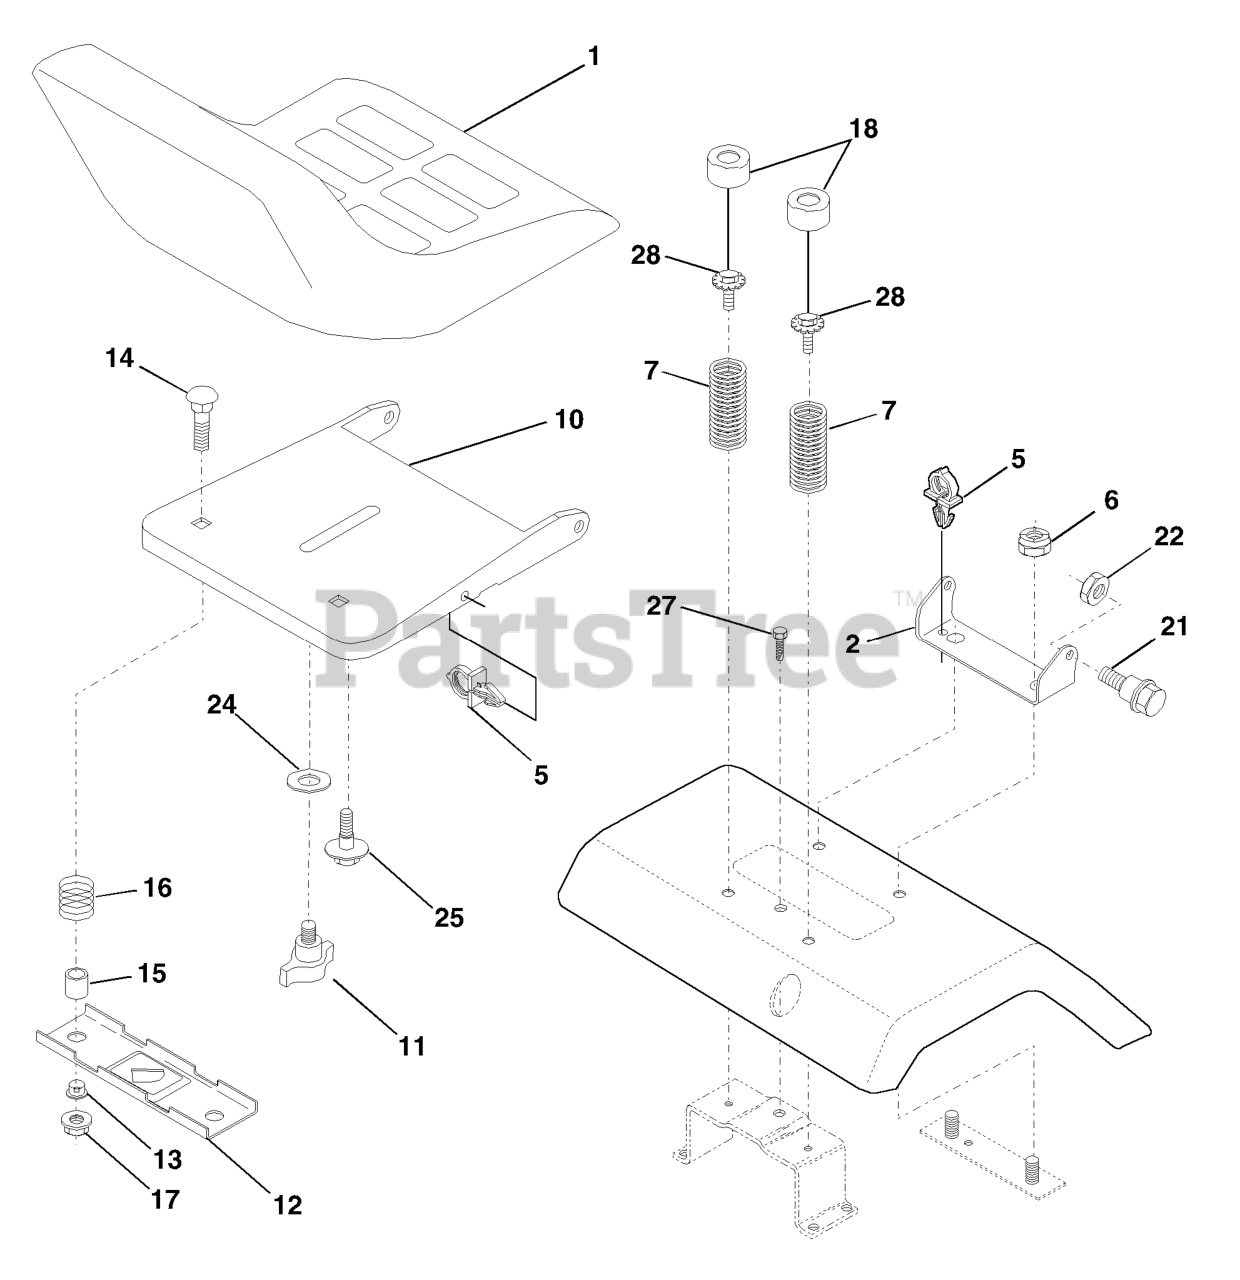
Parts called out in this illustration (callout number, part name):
1	SEAT, GRAY
2	SEAT PIVOT BRKT
6	NUT
7	SPRING COMPRESSION
10	PAN, SEAT
11	KNOB.SEAT.ADJ.WINGNUT
12	BRKT SWITCH
14	BOLT.ROUND.HEAD.SQUARE.NECK
15	SPACER SPLIT
16	SPRING COMPRESSED
17	NUT T
18	CAP SPRING
21	BOLT SHOULDER 5/16-18
22	LOCKNUT
25	BOLT,SHOULD
27	SCREW LT
28	BOLT HEX WASHER HD 5/16-18
